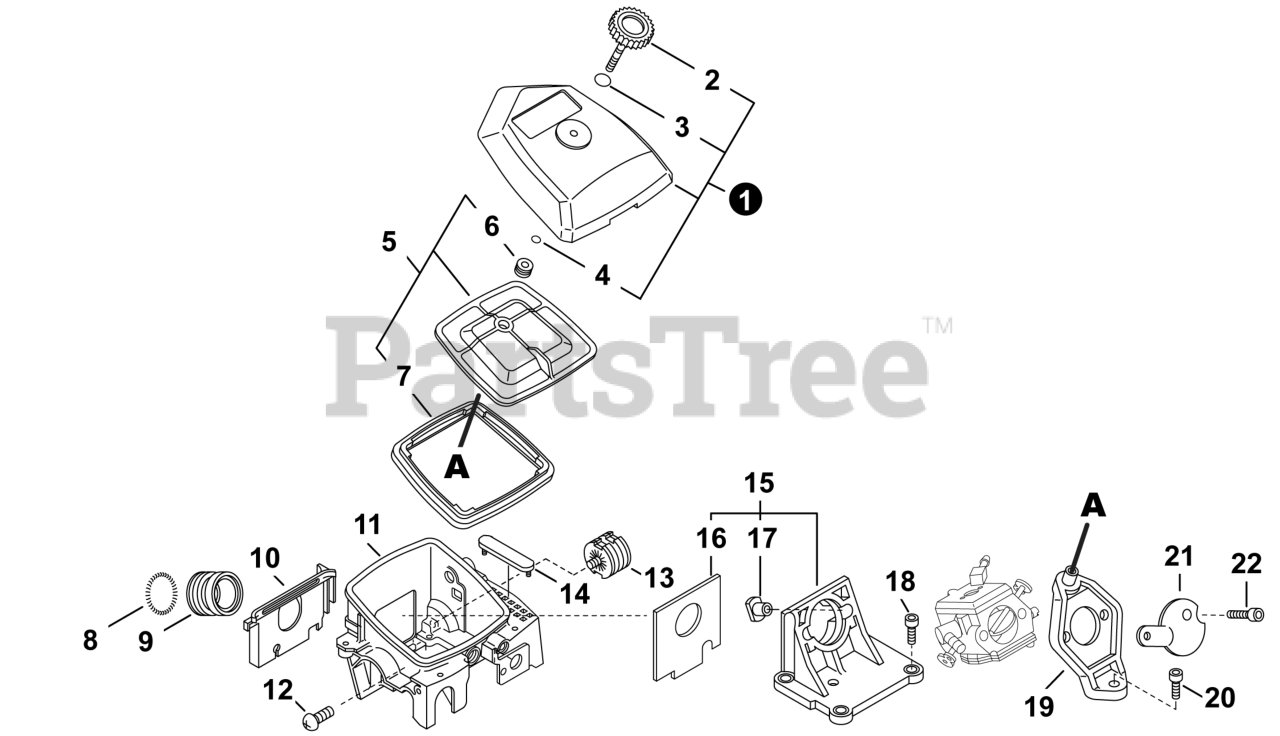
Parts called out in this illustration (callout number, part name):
1	COVER ASSY, AIR FILTER
2	THUMBSCREW
3	O-RING 10
4	O-RING 3
5	FILTER ASSY, AIR
7	SEAL, AIR FILTER
9	ADAPTOR, INTAKE
10	PLATE, GUIDE
11	CASE, CARBURETOR - ORANGE
12	SCREW 4×8
14	PLUG
15	INSULATOR KIT, INTAKE
16	SEAL, DUST
18	BOLT 5×25
19	BRACKET, AIR FILTER
20	BOLT 5×20
22	BOLT 5×55
